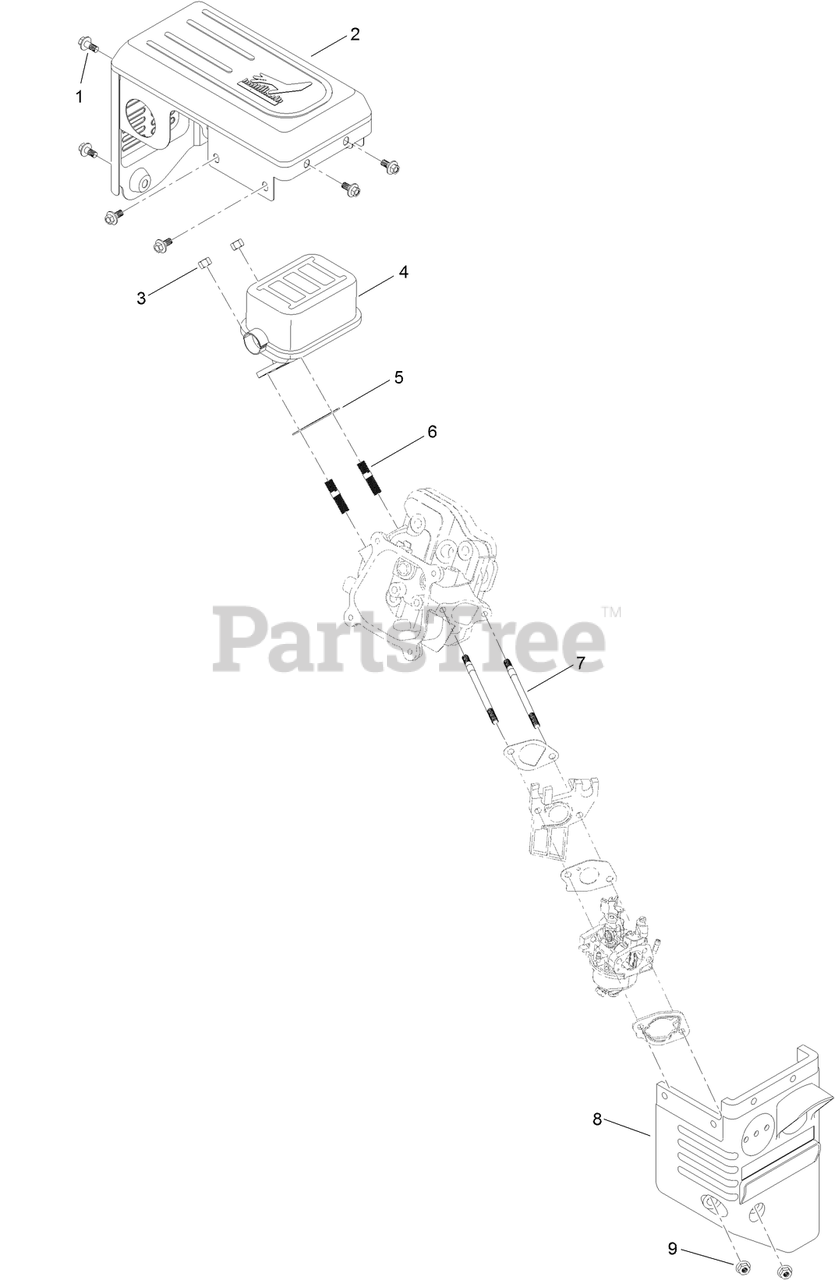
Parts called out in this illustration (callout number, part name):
1	SCREW-HHF
2	GUARD-MUFFLER
3	NUT-HH
4	MUFFLER ASM
5	GASKET-EXHAUST
6	STUD-EXHAUST
7	STUD-INTAKE
8	BOX-HEATER
9	NUT-FLANGE
